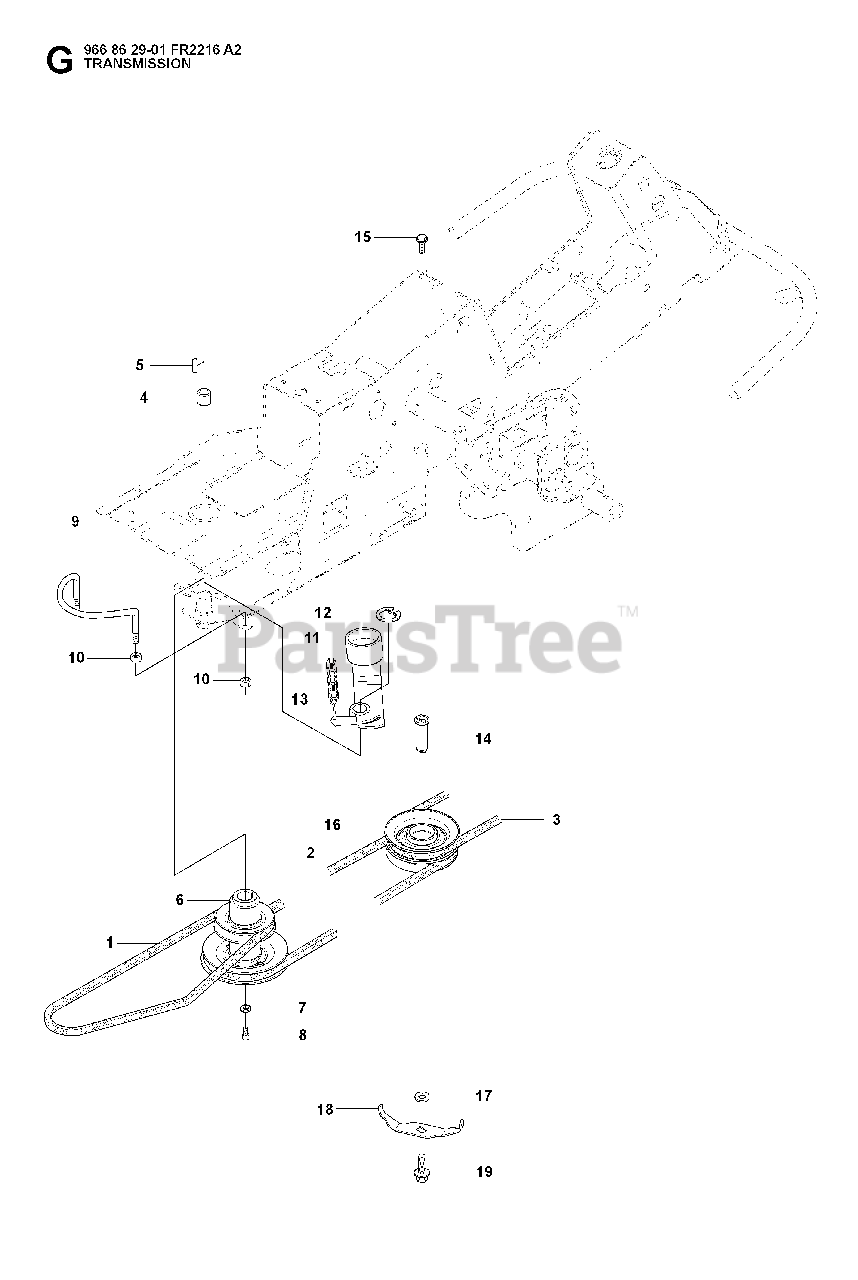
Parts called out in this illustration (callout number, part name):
2	BELT
3	BELT
9	BELT GUIDE
11	TENSIONER
12	RETAINING RING SGA 25
14	SHAFT
18	BELT GUIDE
19	BOLT
